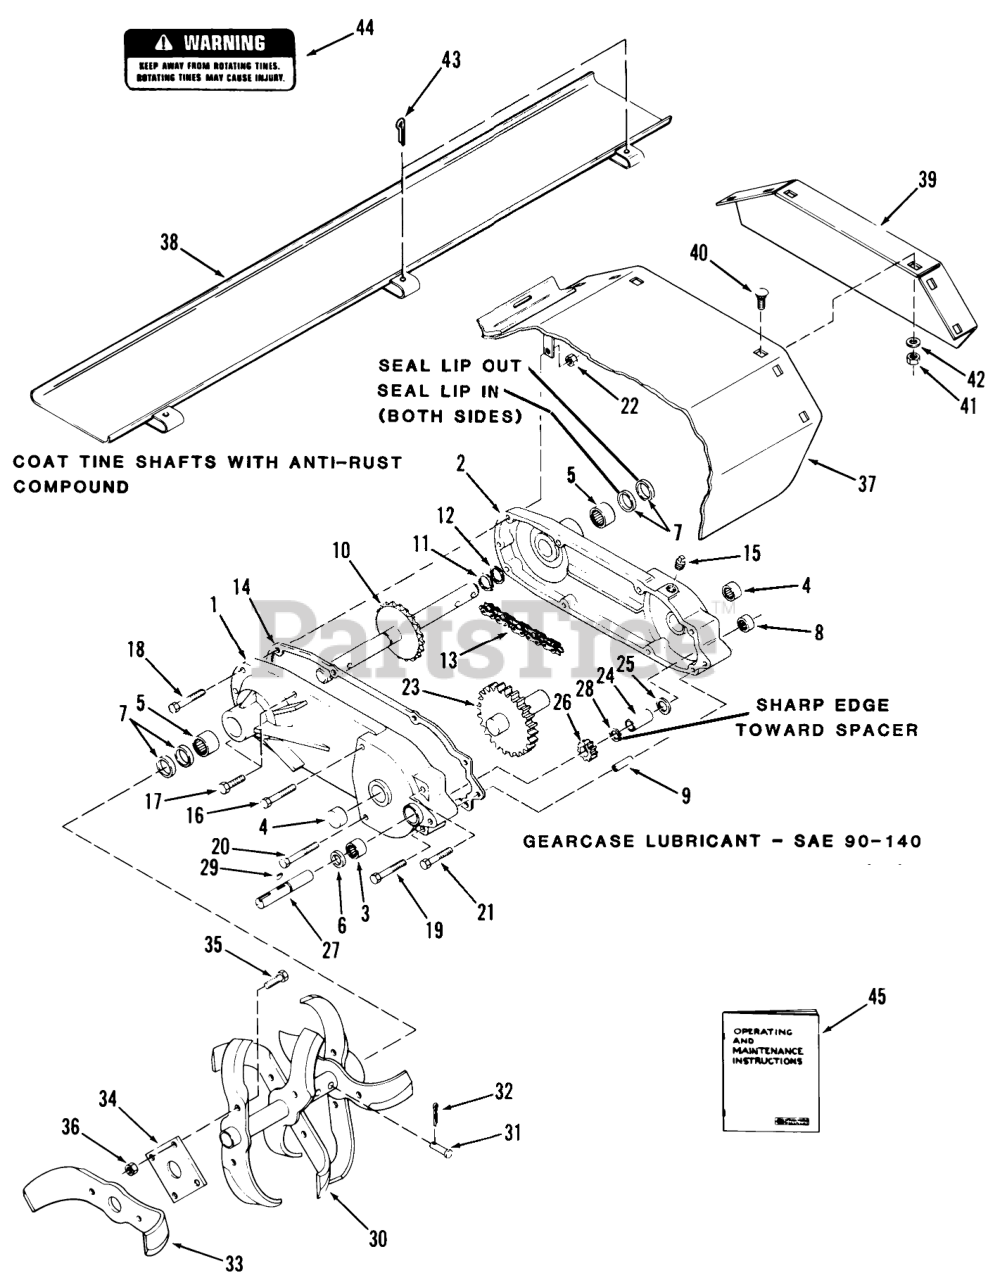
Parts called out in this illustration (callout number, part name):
1	R.H. Case (w/Bearings)
2	L.H. Case (w/Bearings)
3	BEARING-NEEDLE
4	BEARING-NEEDLE
5	BEARING-NEEDLE
6	SEAL-OIL
8	BEARING-NEEDLE
9	ROLL PIN 3/8 X 1
10	TINE SHAFT ASM
11	Snap Ring
12	WASHER
13	CHAIN
14	Gasket
15	SOLID PIPE PLUG
16	H H C S
17	Bolt
18	HHCS
19	BOLT
20	Hex Bolt
22	NUT
23	GEAR AND SHAFT ASM
24	Spacer
25	WASHER-THRUST
26	GEAR-PINION
27	SHAFT-INPUT
28	RING-SNAP, EXTERNAL
29	Key
30	Tine R.H.
31	PIN-CLEVIS
33	R.H. Tine
34	Plate-Tine Mounting
35	H H C S
36	Nut
37	X-REF 92-6514-01
38	Rear Shield
39	Cover-End
40	CARRIAGE BOLT -4
41	Nut
42	WASHER 5/16 SAE
44	Decal-Warning
45	Operating Maintenance Instructions
